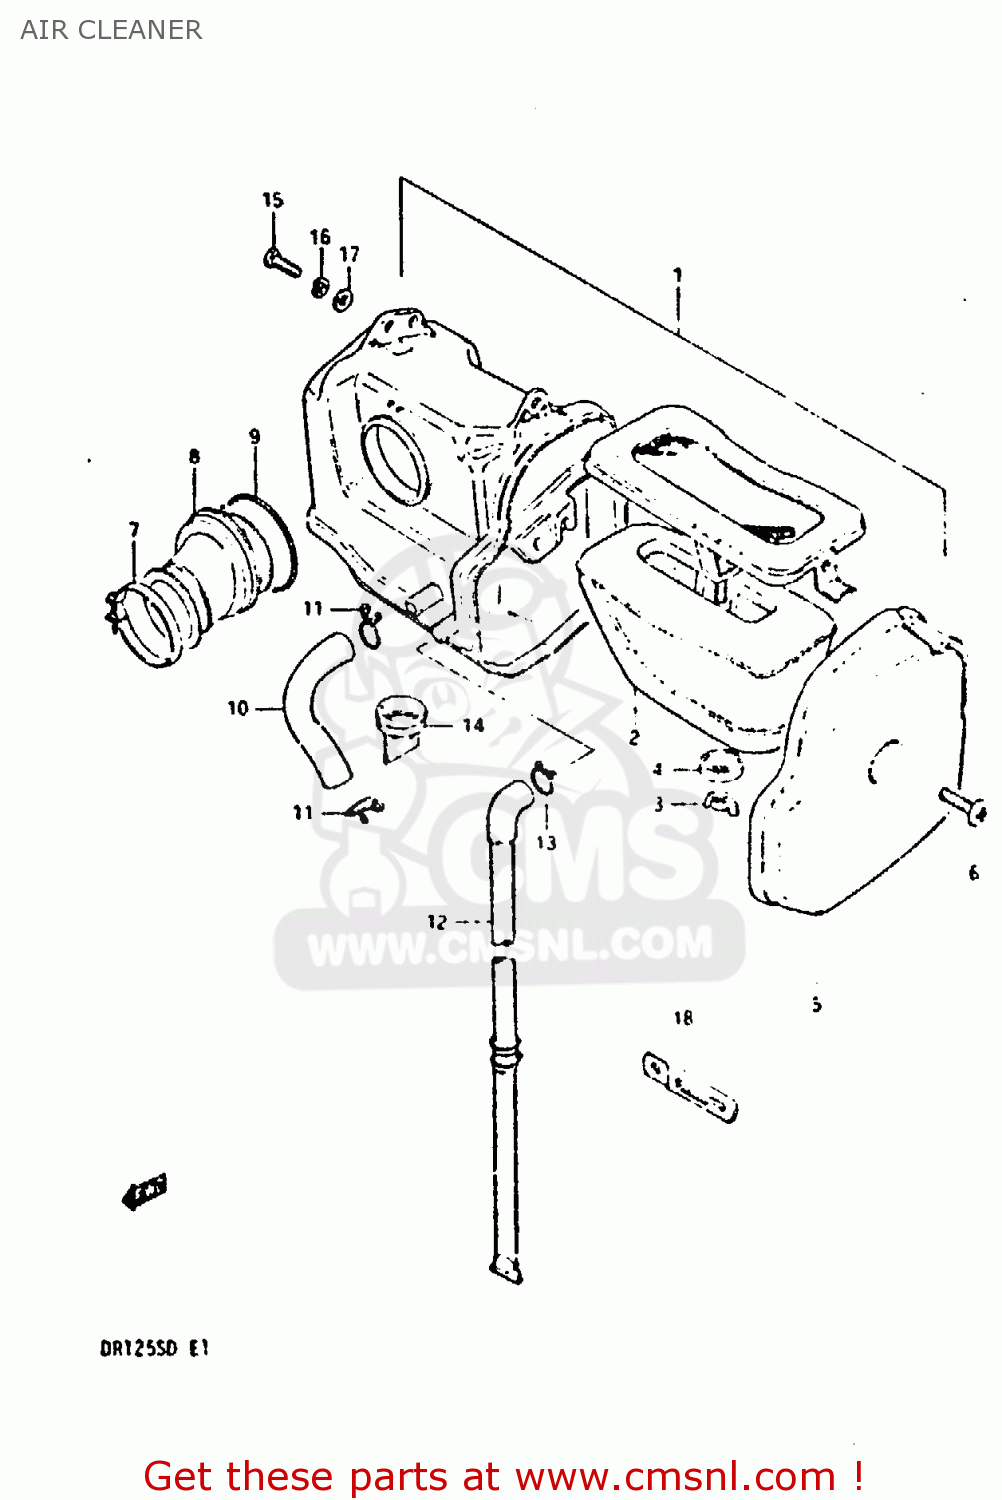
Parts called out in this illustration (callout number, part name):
1	CLEANER ASSEMBLY,AIR
2	ELEMENT,AIR CLEANER
3	NUT
4	WASHER
5	CAP
6	SCREW
7	CLAMP
8	TUBE,OUTLET
9	CLAMP,CLEANER SIDE
10	TUBE,AIR CLEANER BREATER
11	CLAMP
12	HOSE,AIR CLEANER DRAIN
13	CLAMP
14	DRAIN TUBE
15	BOLT, UPPER
16	LOCK WASHER
17	WASHER
18	CLAMP
